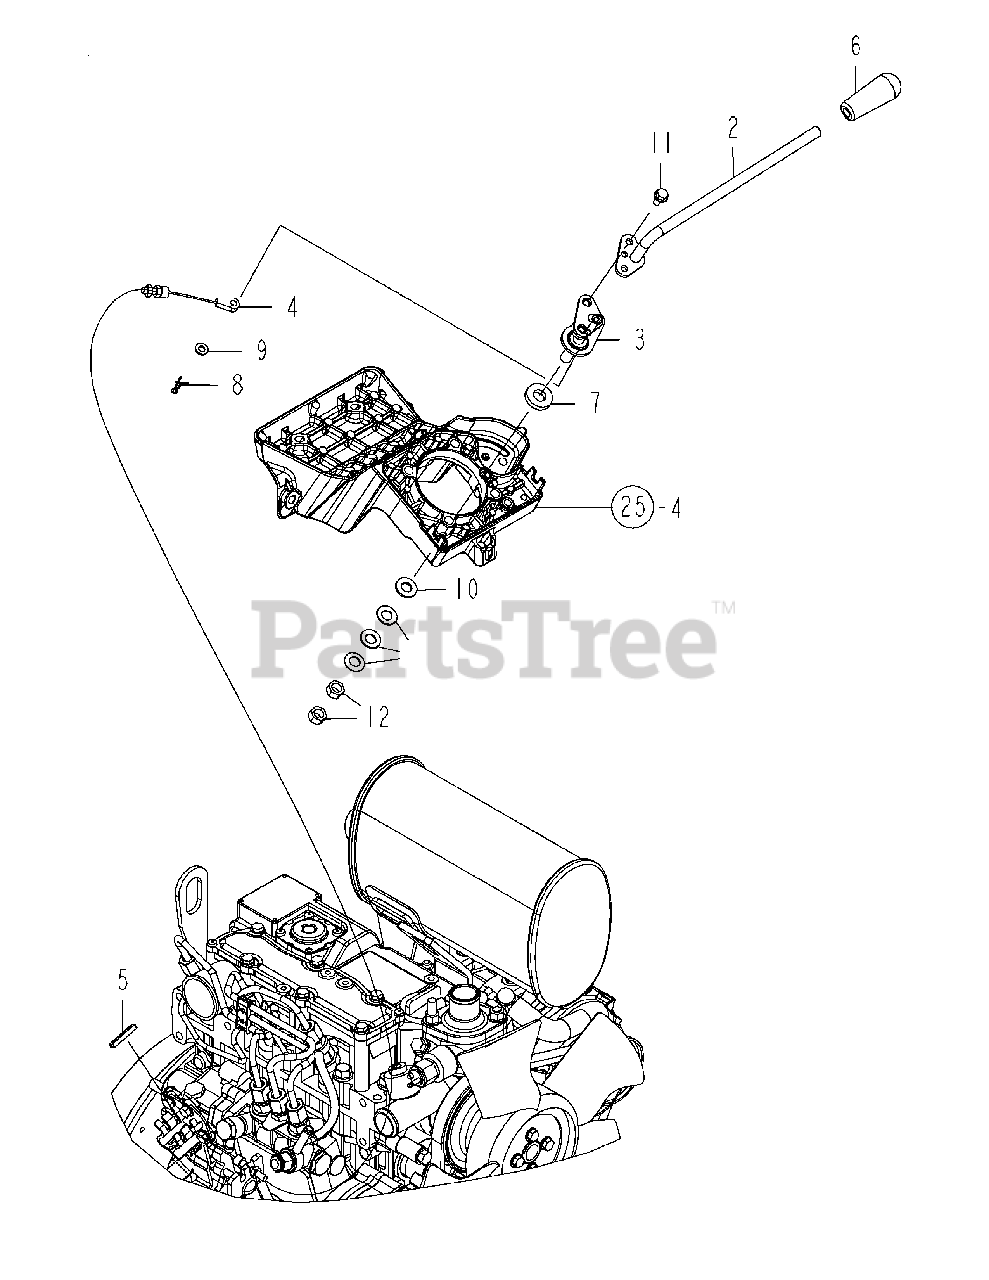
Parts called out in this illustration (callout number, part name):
1	WASHER,CONICAL 10
2	CONTROL LEVER,HEAD
3	CONTROL LEVER,BASE
4	CABLE ASSY,CONTROL
6	KNOB, ACCEL. LEVER
7	SPACER, 13X26X5
